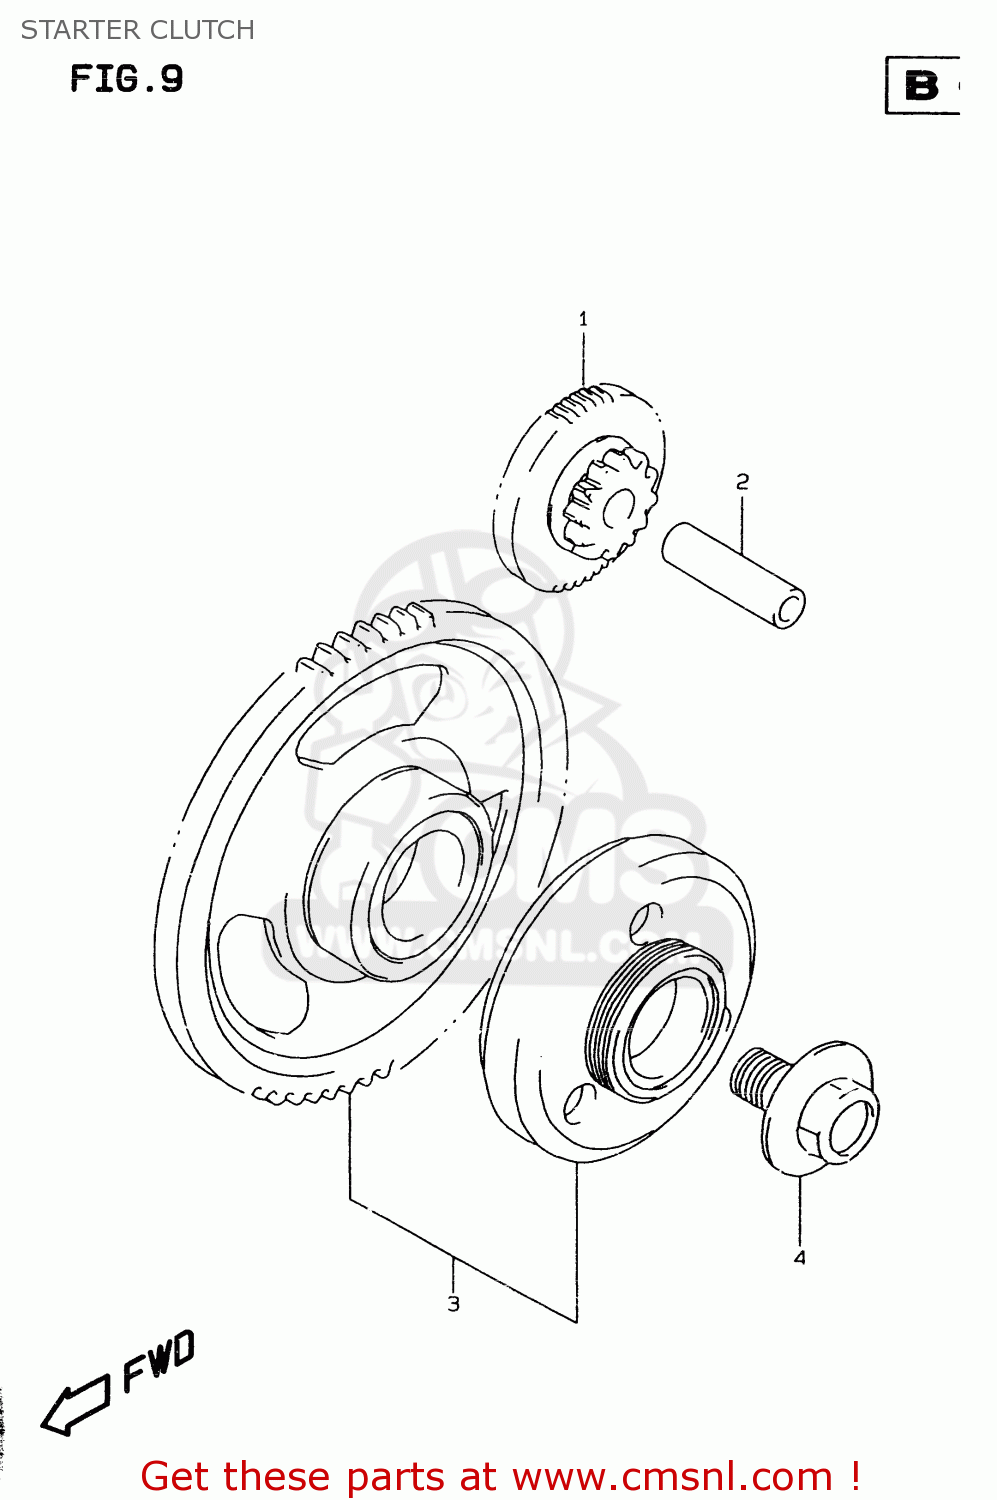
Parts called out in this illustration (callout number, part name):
1	GEAR,STARTER IDLE(NT:12,53)
2	PIN(7X11X42)
3	CLUTCH SET,STARTER
4	BOLT(14X21)
